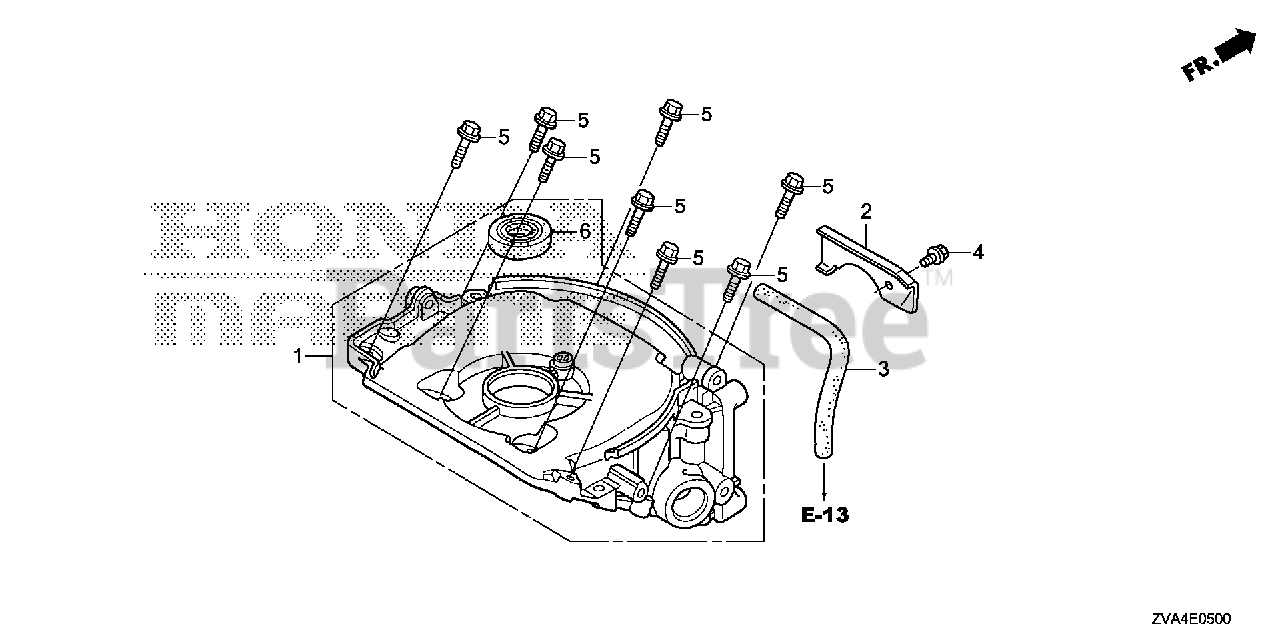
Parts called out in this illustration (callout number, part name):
1	CASE ASSY., OIL
2	PLATE, TUBE SETTING
3	TUBE, CLUTCH HOUSING BREATHER
4	BOLT, FLANGE (5X10)
5	BOLT, FLANGE (5X23) (CT200)
6	OIL SEAL (17X27X5) (KOYO)
